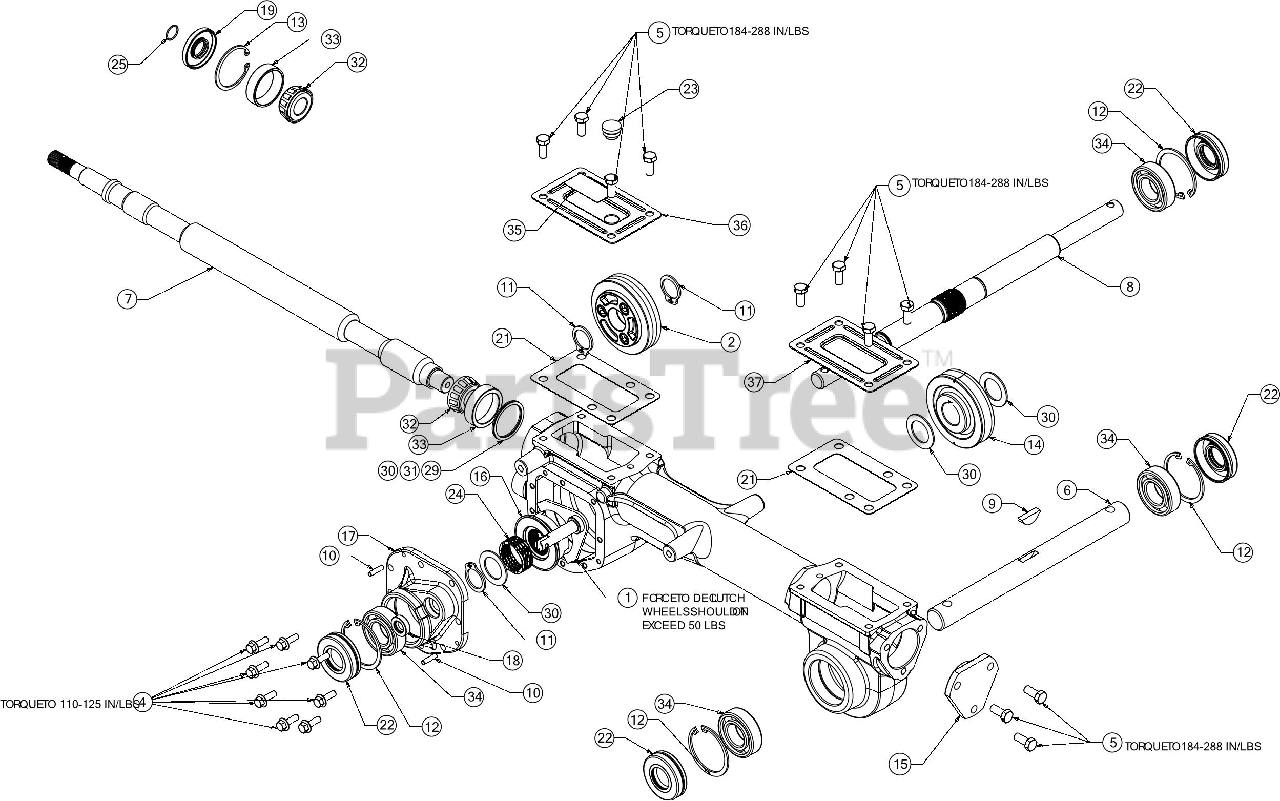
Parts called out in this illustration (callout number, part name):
1	WHEEL DRIVE SHAFT YOKE ASSEMBLY
2	WORM GEAR ASSEMBLY
2	SCREW 5/16-18X.625
3	TILLER TRANSMISSION HOUSING
4	SCREW 1/4-20 x .75 GR5
5	SCREW 5/16-18 x .75 GR5
6	TILLER SHAFT
7	WORM DRIVE SHAFT
8	WHEEL AXLE SHAFT
9	KEY-HI PRO .25 x 1
10	DOWEL PIN
11	RETAINING RING
12	RETAINING RING
13	RETAINING RING
14	WORM GEAR (LH) 30T
15	BEARING COVER
16	DISCONNECT COLLAR
17	TILLER HOUSING COVER
18	OIL SEAL .5000 x .8750 x .2500
19	OIL SEAL .750 SHF x 1.783
21	GEAR HOUSING GASKET
22	OIL SEAL 1.00 SHF x 2.00 BORE
23	RUBBER OIL PLUG
24	WHEEL DRIVE SPRING
25	WIRE RING
26	FLAT WASHER 1.500X1.750X.062
27	FLAT WASHER 1.500X1.750X.005
28	FLAT WASHER 1.500X1.750X.030
29	FLAT WASHER 1.500X1.750X0.010
30	WASHER 1.010X1.560X.060
32	BEARING CONE
33	BEARING CUP
34	BALL BEARING
35	LABEL
36	TRANSMISSION COVER
37	TRANSMISSION COVER
